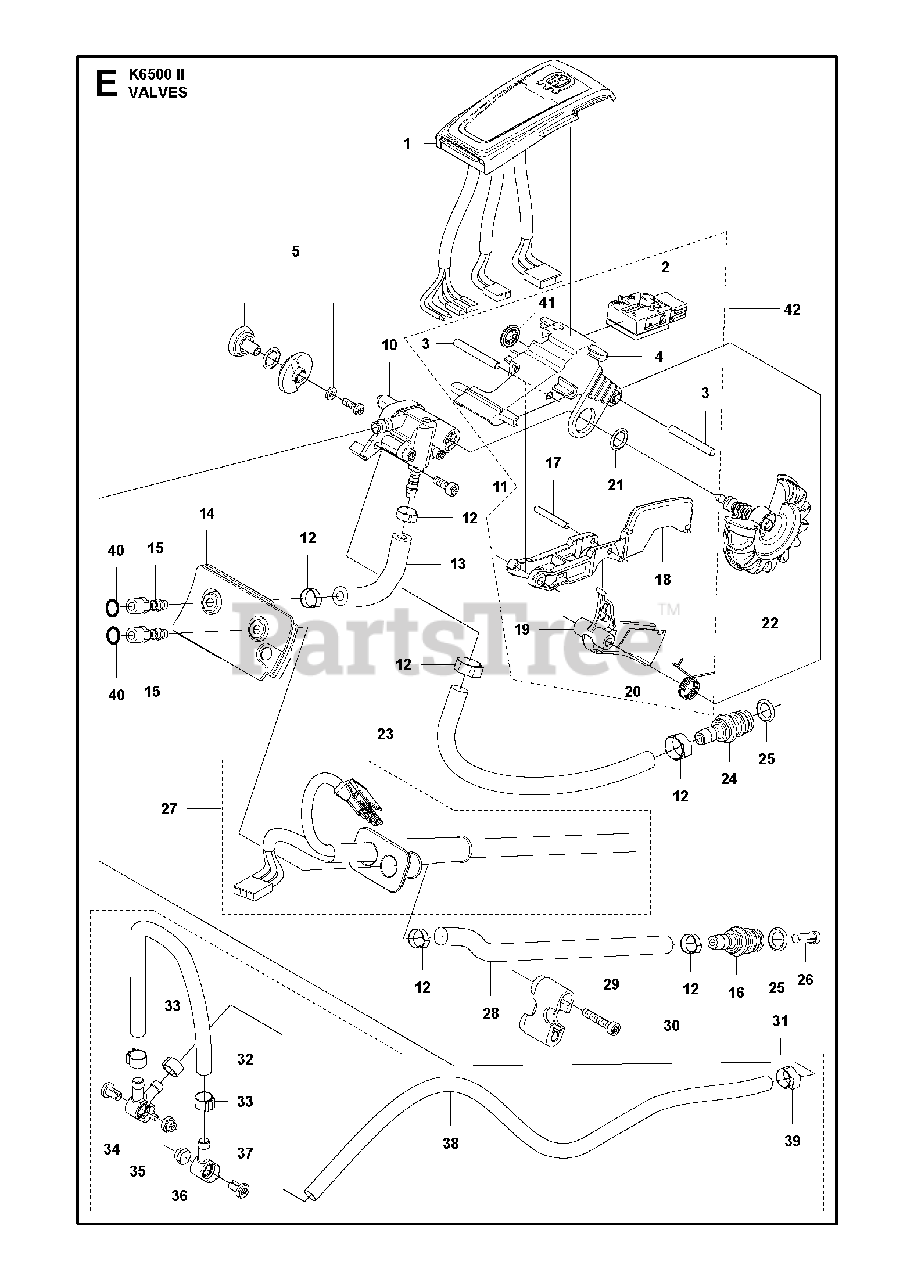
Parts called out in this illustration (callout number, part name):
3	PARALLEL PIN
11	SCREW ITXSCT
17	PARALLEL PIN
30	SCREW ITXSCT
34	SCREW ITXSCM
